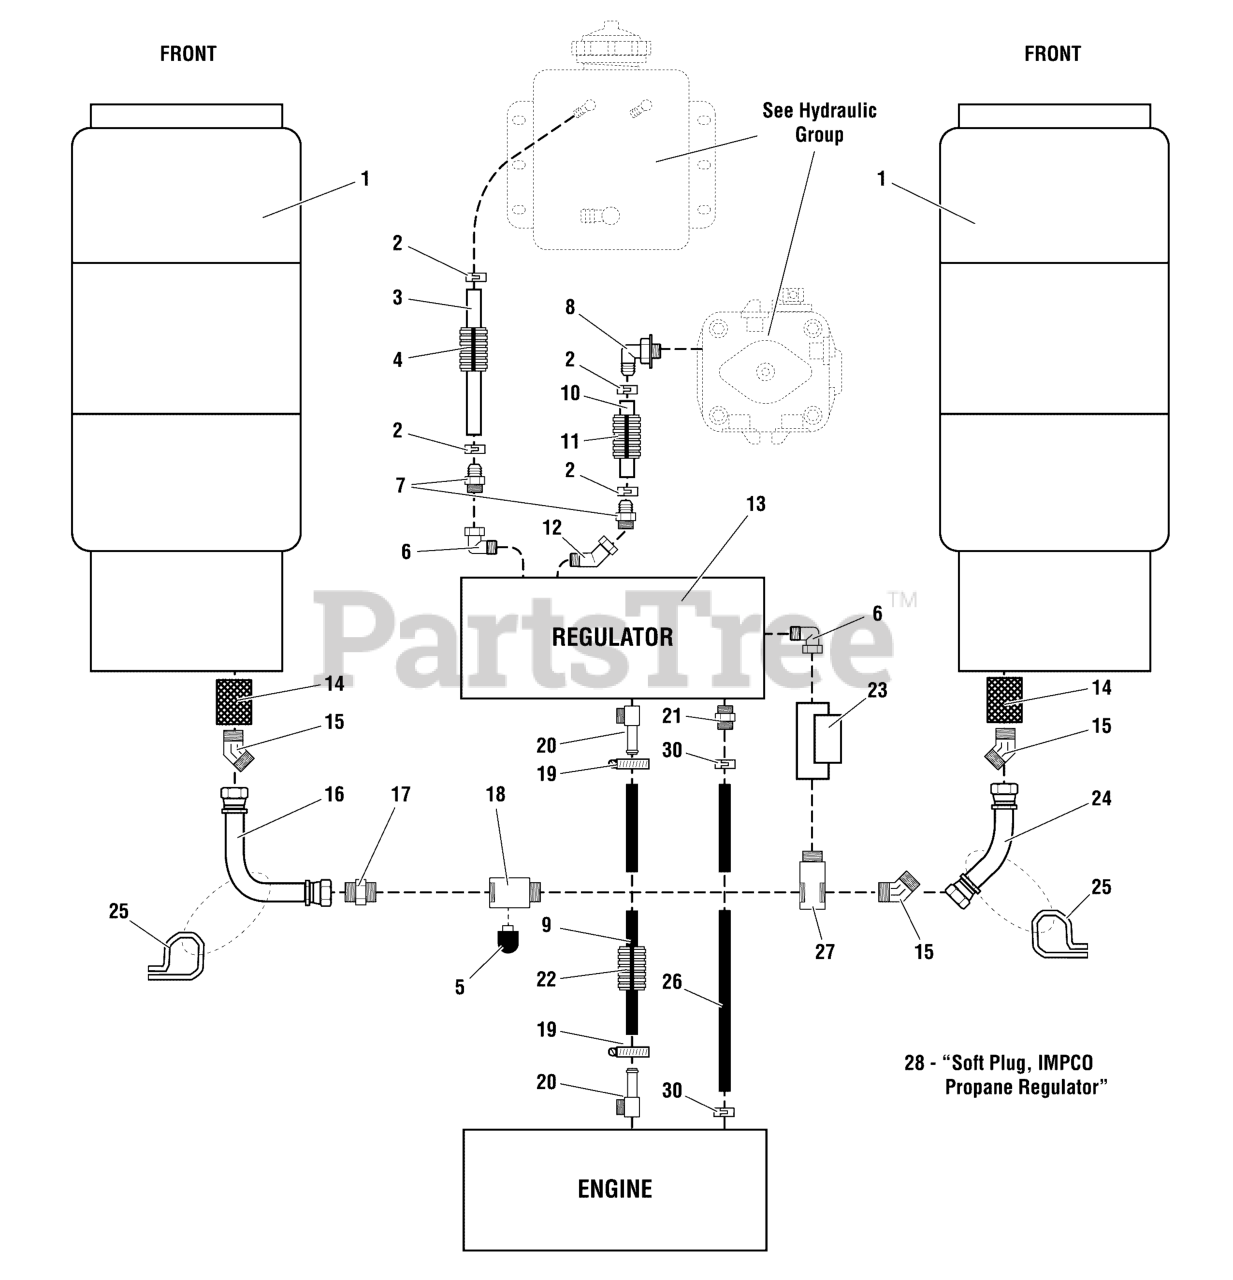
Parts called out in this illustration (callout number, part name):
1	TANK, PROPANE - WORTHINGTON
2	CLAMP, Hose
3	HOSE, 3/8" PUSH-LOCK, 29.00"
4	WIRE LOOM, 5/8" ID, 25" LONG
5	RELIEF VALVE, PROPANE
6	FITTING, 1/4 NPT STREET ELBOW, PLATED STEEL
7	FITTING, 3/8 HOSE BARB X 1/4NPT, BRASS
8	ADAPTER, 90 DEG. 9/16 - 3/8 BARB
9	HOSE, LOW PRESSURE FUEL X 33.25, PROPANE
10	HOSE, 3/8" PUSH-LOCK, 11.00"
11	WIRE LOOM, 5/8" ID, 11" LONG
12	FITTING, 1/4NPT X 45, STREET ELBOW BRASS
13	REGULATOR, PROPANE
14	COUPLING, PROPANE TANK
15	FITTING, TEE, 1/4 NPTM X 45 ELBOW BRASS
16	HOSE, LH FUEL SUPPLY ASM X 16.62 PROPANE
17	FITTING, 1/4 NPTM STRAIGHT, BRASS
18	FITTING, 1/4" NPT STREET TEE, PLATED STEEL
19	CLAMP, #10 HOSE, STAINLESS
20	FITTING, 3/8NPT-1/2 HOSE, BARB PLATED STEEL
21	FITTING, 1/4 HOSE BARB X 1/8NPT, BRASS
22	LOOM, CONVOLUTED SPLIT, 1" ID
23	VALVE, LOCK OFF ASSEMBLY
24	HOSE, RH FUEL SUPPLY ASM X 36, PROPANE
25	CLAMP, VINYL INSULATED, 1.00
26	HOSE, 1/4 ID VAC HOSE X 29, PROPANE
27	FITTING, TEE, 1/4 NPT, PLATED STEEL
30	CLAMP, Hose
